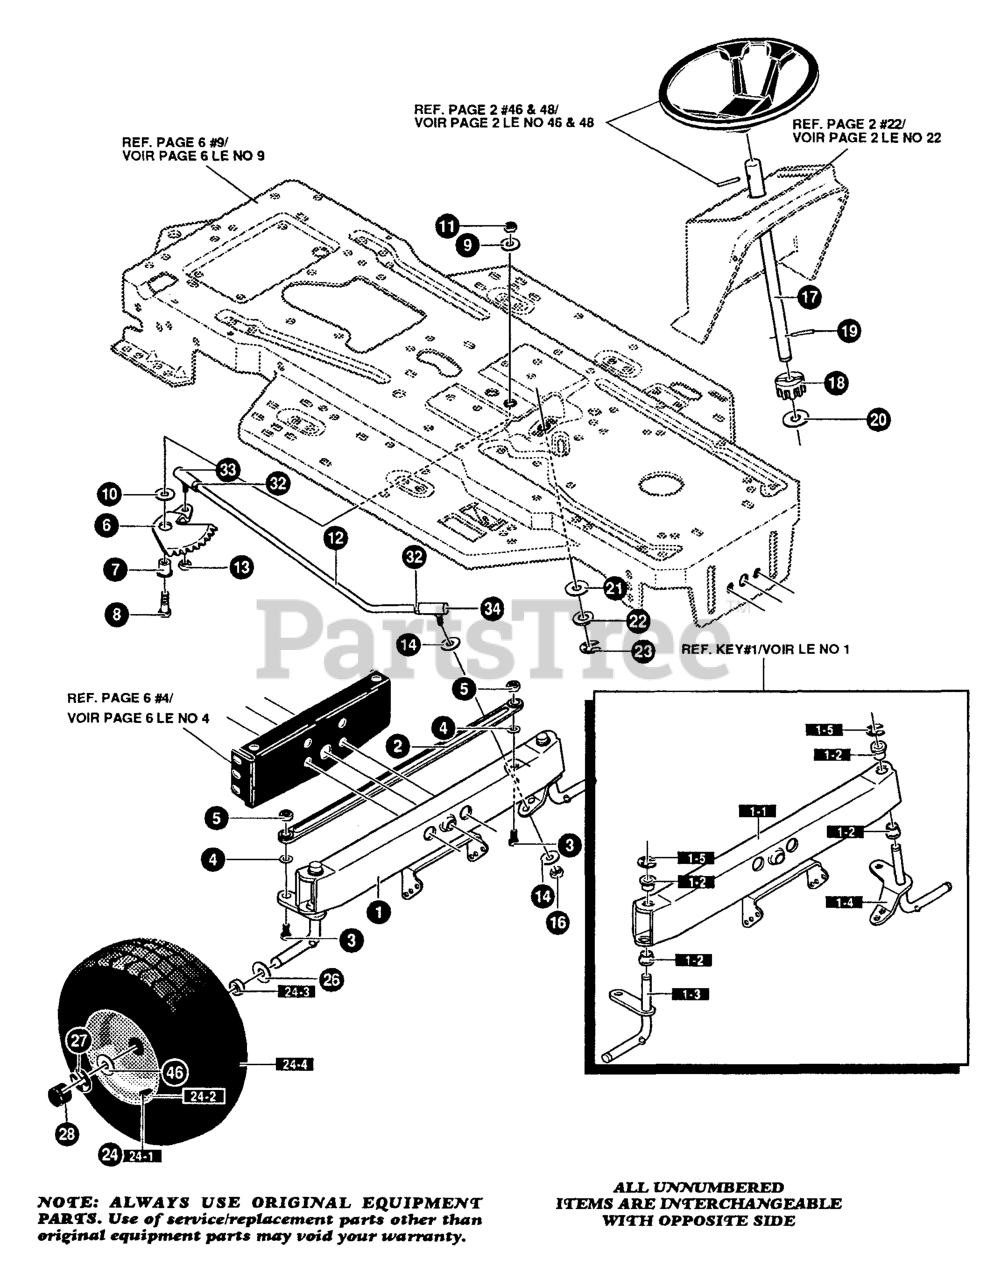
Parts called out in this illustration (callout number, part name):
1	AXLE, FRONT ASSY
1-1	FRONT AXLE
1-2	SPINDLE BEARING
1-3	ASSY, SPINDLE, RH
1-4	ASSY, SPINDLE, LH
1-5	RING, RETEX
2	TIE ROD ASSY
4	WASHER
5	NUT
6	SECTOR, STEER
7	BEARING
10	WASHER
12	STEERING LINK
14	WASHER
17	SHAFT, STEERING
18	PINION, STEER
19	PIN, DOWEL
20	BEARING
22	WASHER
23	RING, RETEX
24	TIRE 67 RIM
24-1	VALVE STEM
24-2	RIM, WHEEL
24-3	BEARING
26	WASHER
27	RING, RETEX
28	HUB CAP
33	BALL JOINT
34	BALL JOINT
